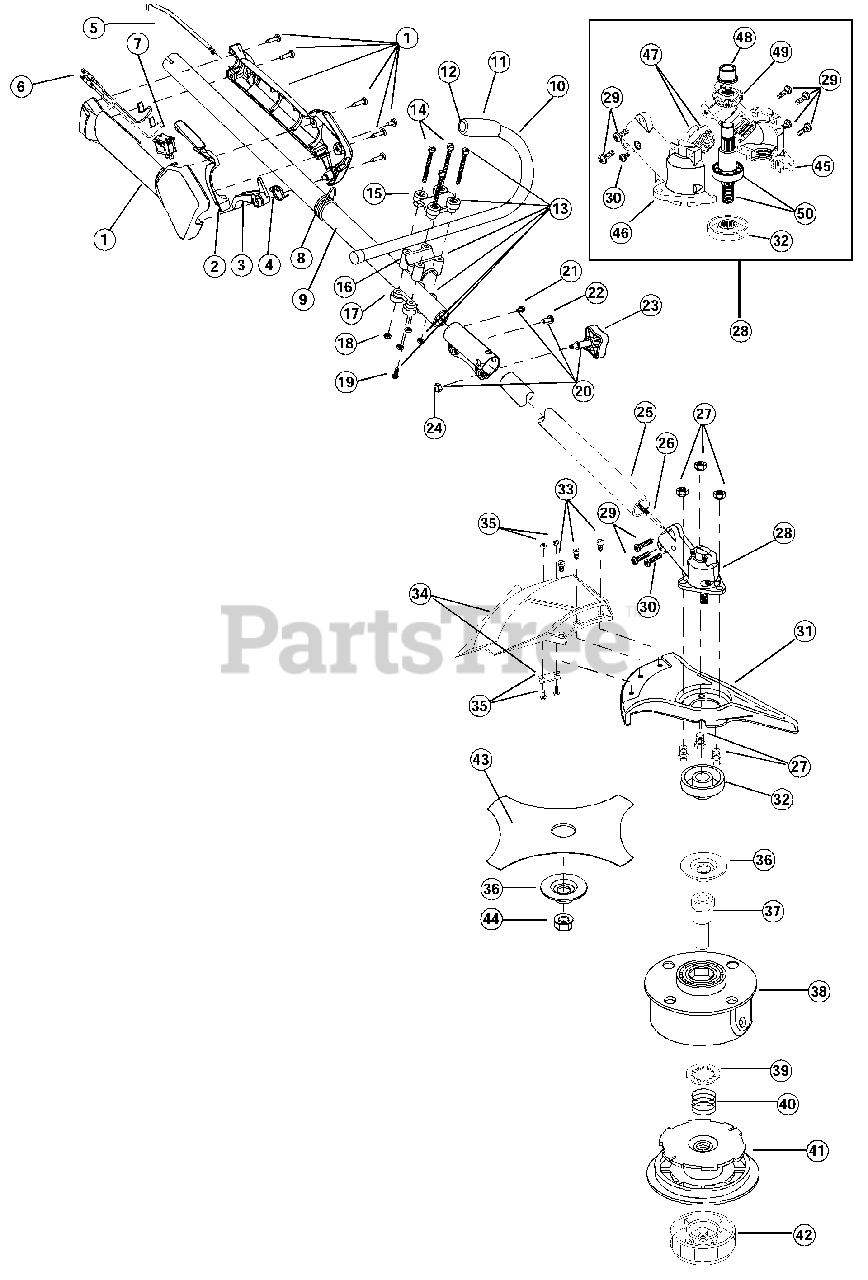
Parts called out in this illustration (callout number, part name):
1	Throttle Housing & Trigger Assembly
2	Throttle Trigger Lock-Out
3	Throttle Trigger
4	Throttle Trigger Spring
5	Throttle Cable Assembly
6	Lead Wire Assembly
7	Switch Assembly
8	Harness Clip
9	Upper Drive Shaft Housing Assembly
10	J-Handle Assembly
12	Tube Closure
13	Handle Bracket Assembly
15	Upper Handle Clamp
16	Middle Handle Clamp
17	Lower Handle Clamp
19	Anti-Rotation Screw
20	Split-Boom Coupler
23	Adjustment Knob
24	Knob Retaining Nut
25	Lower Drive Shaft Housing Assembly
26	Lower Flexible Drive Shaft
27	Shield Mount Screw Assembly
28	2 piece Gearbox Assembly
29	Gearbox Mounting Hardware
30	Anti-Rotation Screw
31	Blade Shield/Shield Mount
32	Blade Driver
33	Shield Mounting Screw
34	Shield and Blade Assembly
35	Blade Assembly
36	Retaining Washer
37	Spool Shaft
38	Outer Spool and Eyelet Assembly
39	Retainer
41	Inner Reel
42	Bump Head Knob Assembly
43	4-Tooth Blade
44	Nut
45	Left Housing
46	Right Housing
47	Pinion Gear Assembly
48	Output Shaft Bushing
49	Output Shaft Gear
50	Output Shaft Assembly
